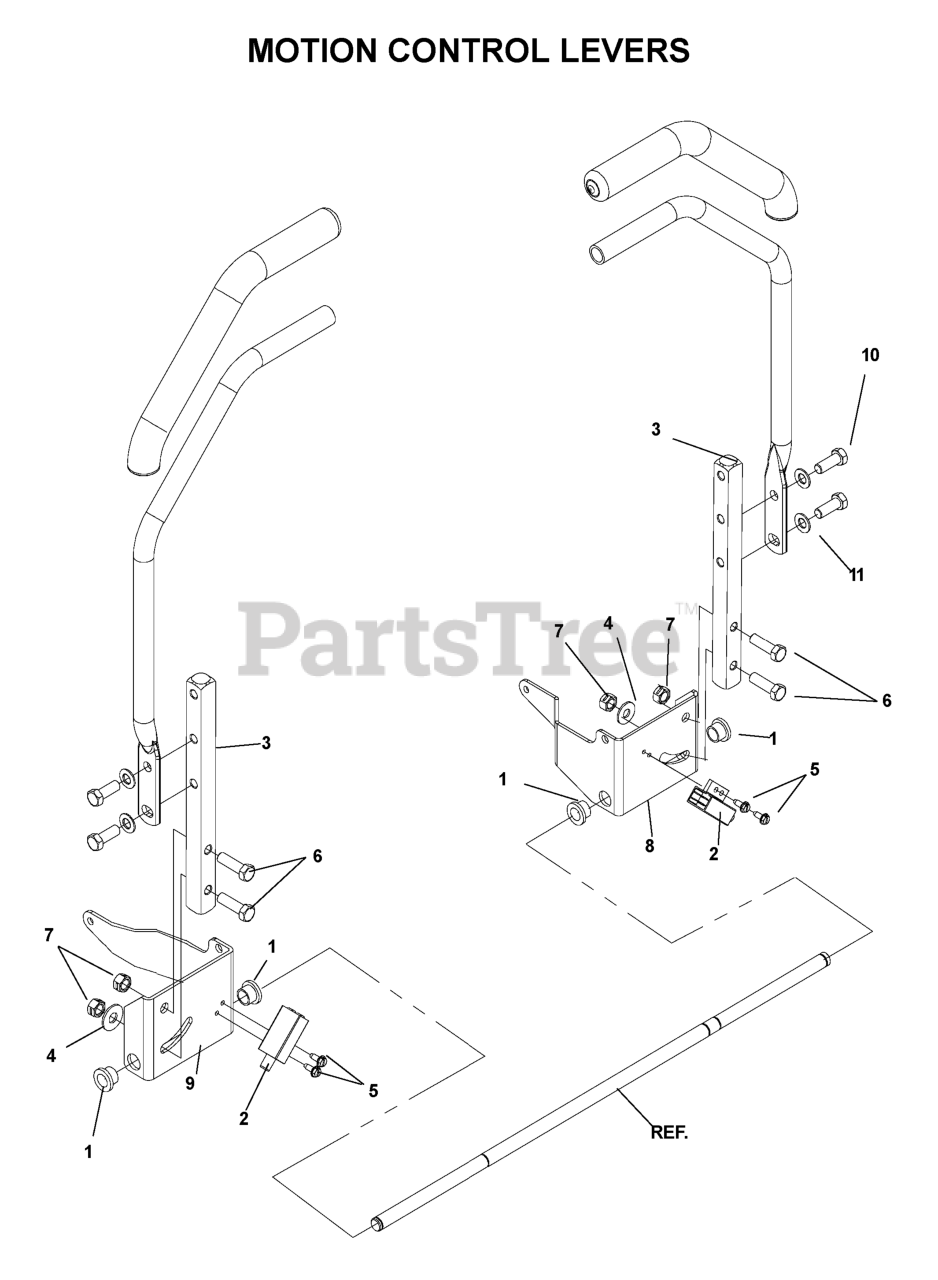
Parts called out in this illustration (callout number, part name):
1	BUSHING, FLANGED NYLON
2	SWITCH, INTERLOCK
3	CONTROL ARM
4	WASHER 5/16 FLAT
5	SCREW #10 X 1/2 SELF TAPPING
6	TAP BOLT 3/8C X 1.5
7	NUT 3/8C CENTERBLOCK
8	CONTROL BRKT-LH
9	CONTROL BRKT-RH
10	HCS 3/8-16X1.GRD.5.ZD
11	WASHER, 3/8 DISC SPRING SPEC
